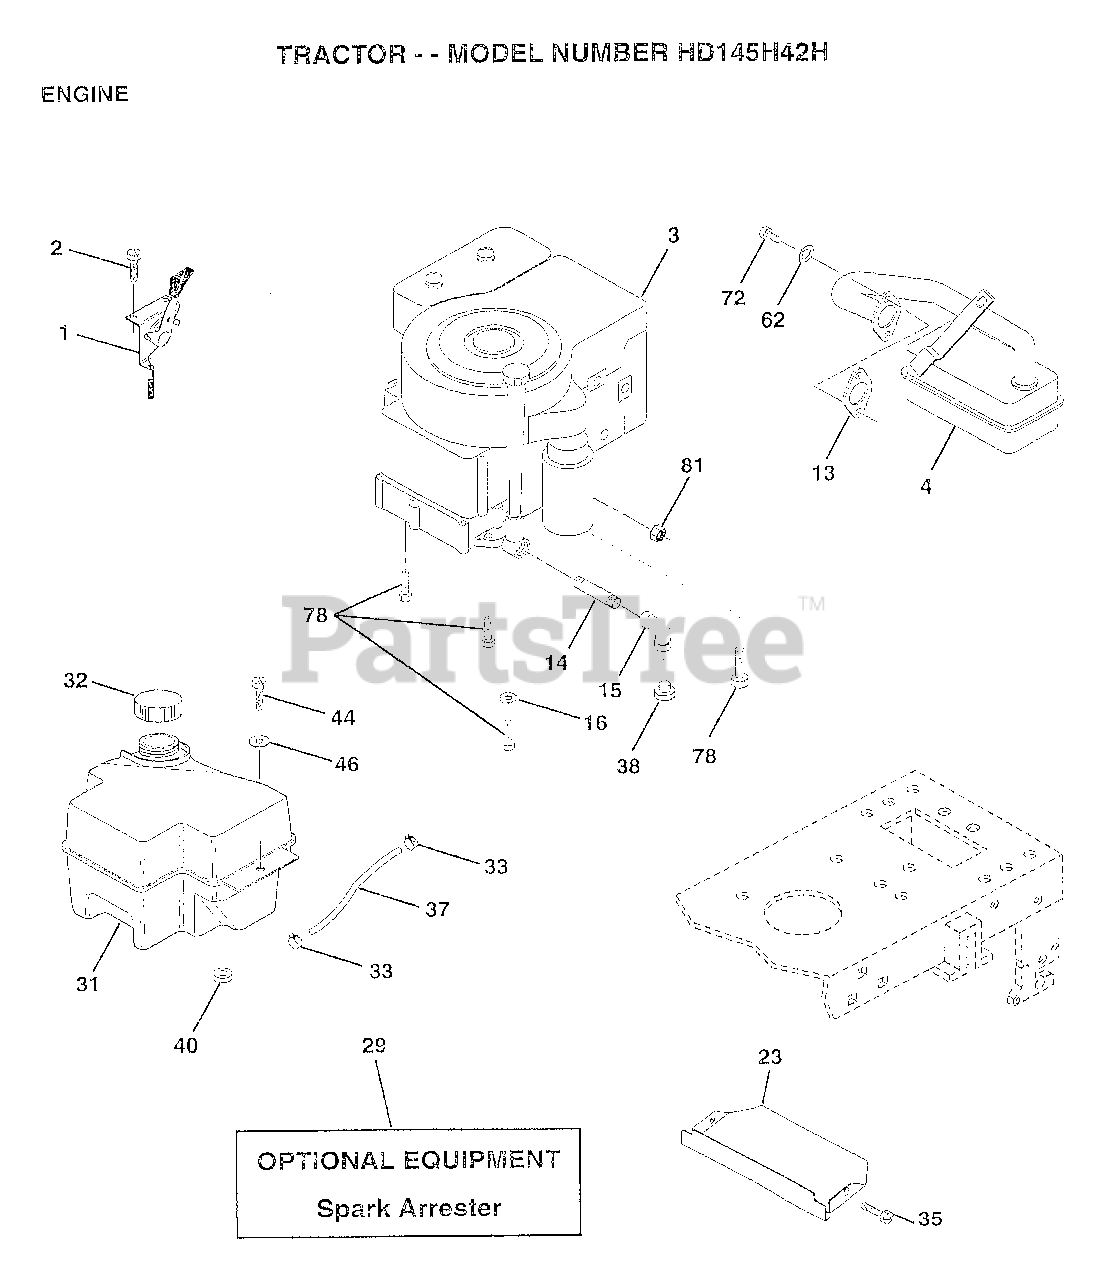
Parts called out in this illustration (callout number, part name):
1	CONTROL THROTTLE
2	SCREW LT
4	MUFFLER
13	GASKET ENG 1 313 LD TIN PLATED
14	PIPE NIPPLE
15	ELBOW
16	LOCKWASHER
23	SHIELD.BRN/DBR.GD
31	TANK.FUEL.FRONT.
32	CAP ASM FUEL
33	HOSE CLAMP
35	SCREW
37	LINE FUEL
44	SCREW HEX CRT
46	WASHER
62	LOCKWASHER
72	SCREW
78	SCREW
81	NUT
